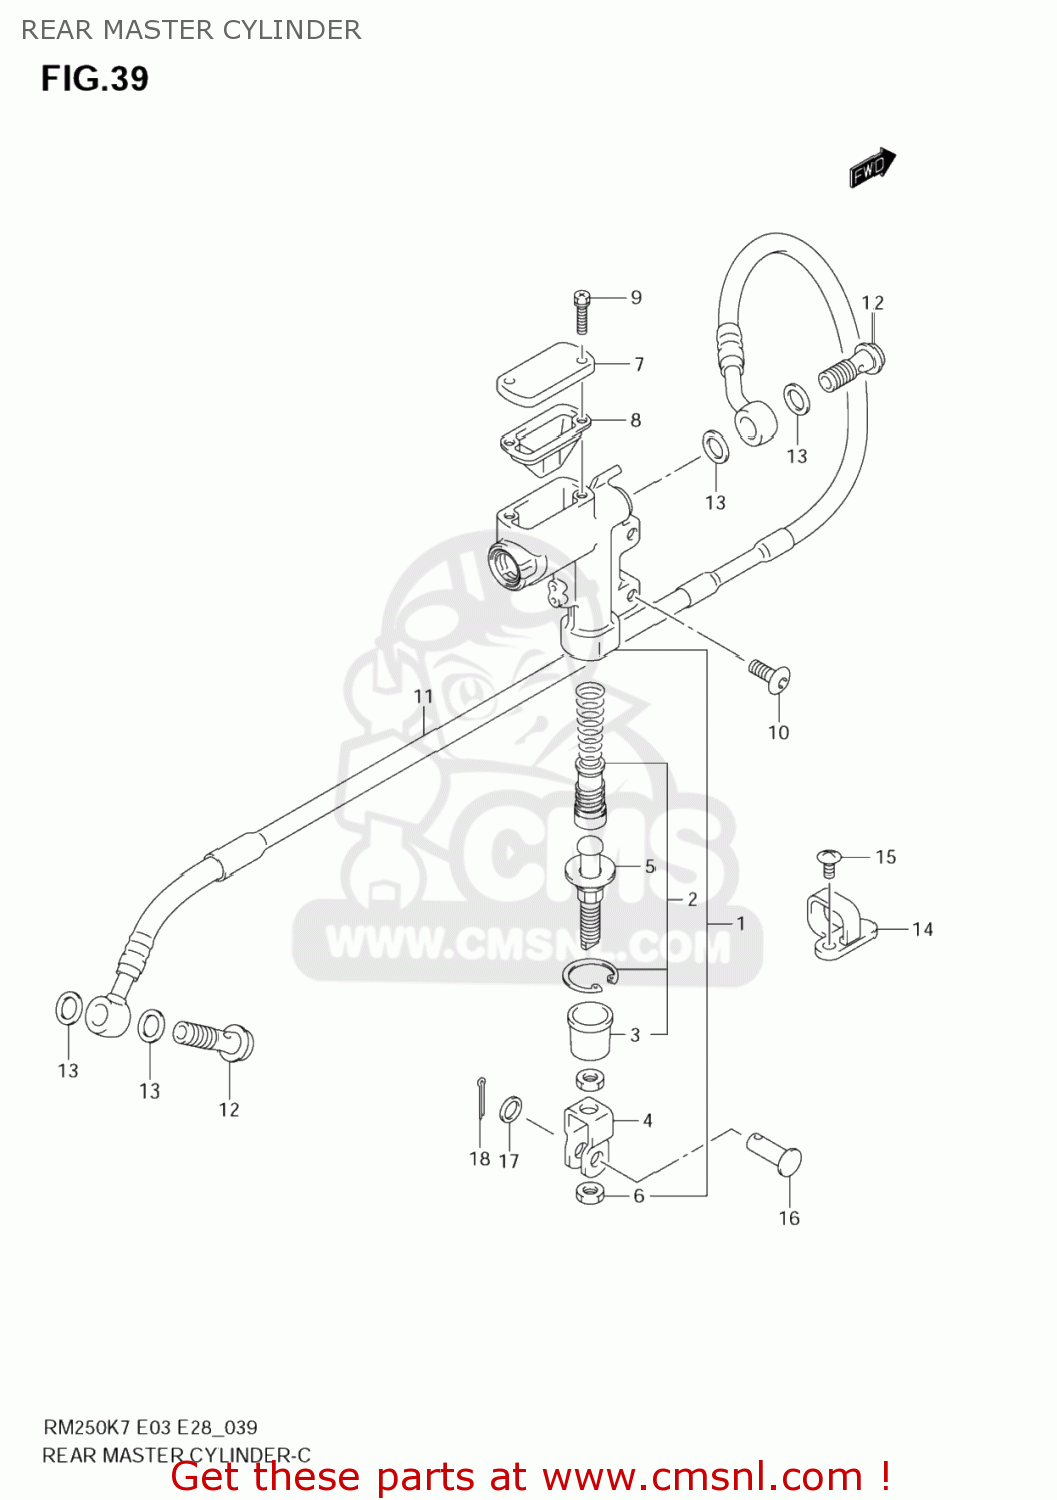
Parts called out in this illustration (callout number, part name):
1	CYLINDER SET,RR MASTER
2	PISTON/CUP SET
3	BOOT
4	YOKE
5	ROD,PUSH
6	NUT
7	CAP
8	DIAPHRAGM
9	SCREW
10	SCREW(6X16)
11	HOSE COMP,REAR
12	BOLT UNION
13	WASHER(10X15X1.5)
14	GUIDE,RR BRAKE
15	SCREW
16	PIN(8X20)
17	WASHER (8.5X14X1.6)
18	PIN
